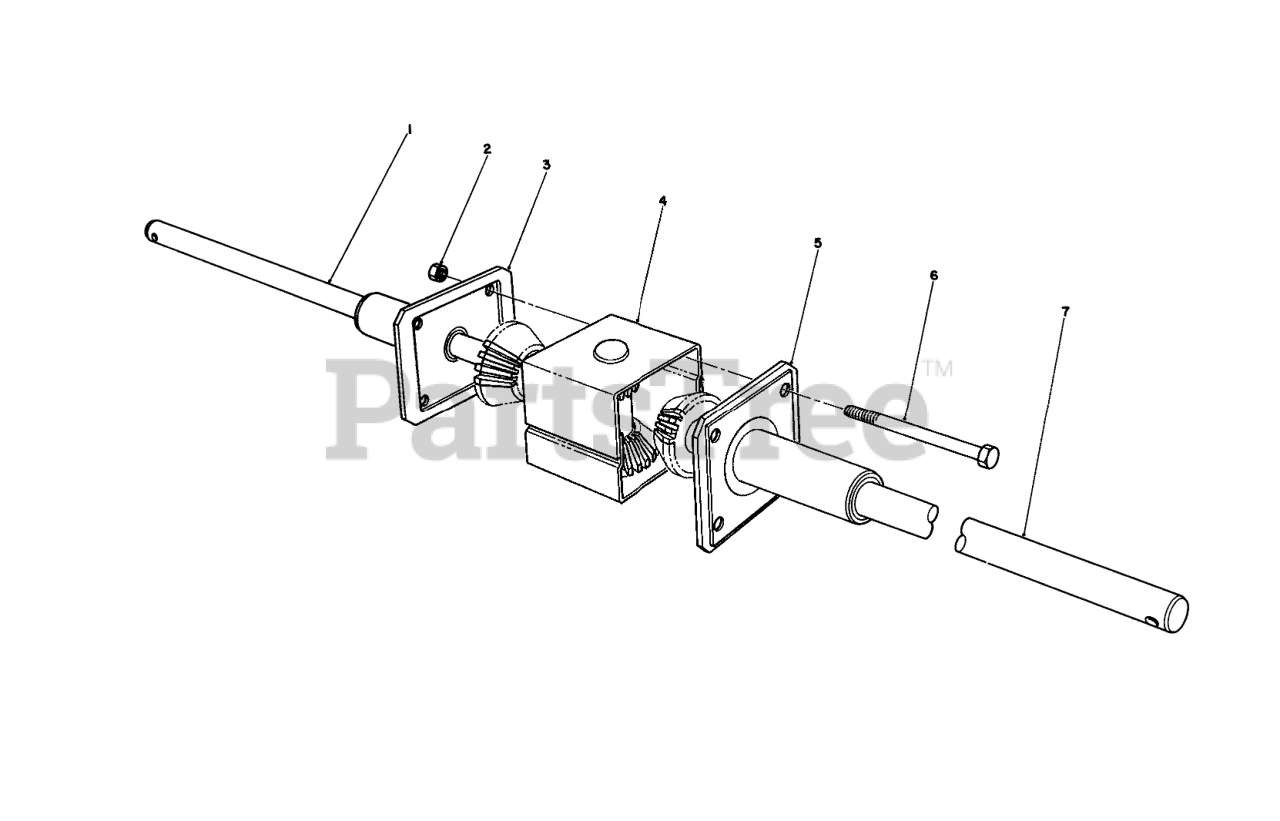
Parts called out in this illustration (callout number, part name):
2	NUT-LOCK, CONE
3	END CAP/BRG ASM
4	GEAR CASE ASM
5	END CAP &BEARING ASY
6	SCREW-HH
